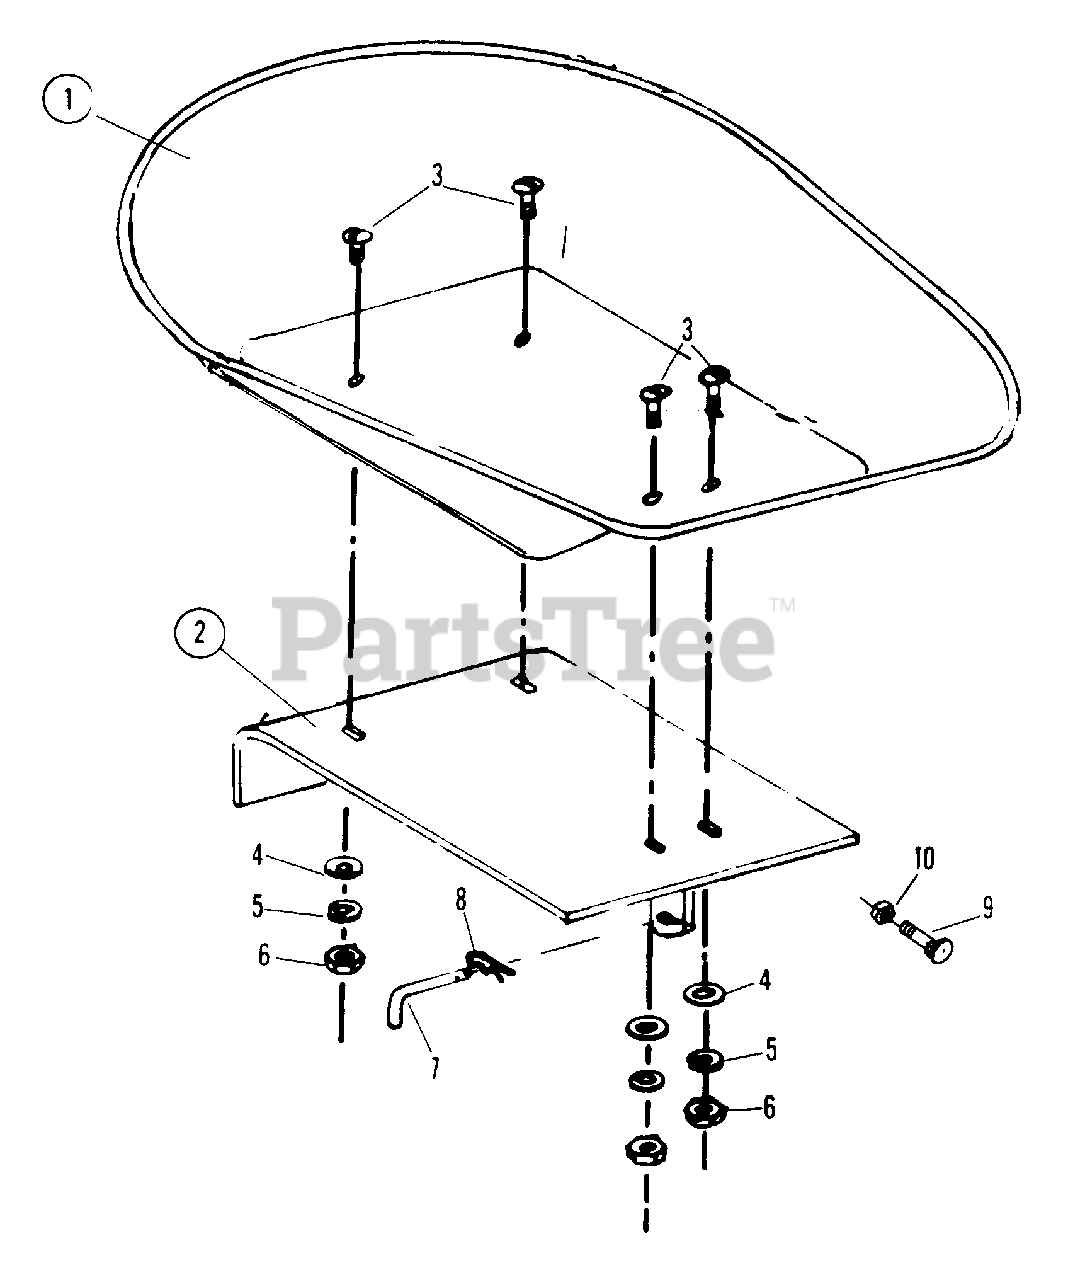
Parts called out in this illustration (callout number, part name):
1	TRAY, DUMP BARROW HAULING
2	BRACKET, TRAY MOUNTING
3	SCREW, 3/8 x 3/4 PAN HEAD MACHINE
4	WASHER, 3/8 PLAIN
5	LOCKWASHER, 3/8"
6	NUT, 3/8 HEX
7	L-PIN .5" Dia.
8	COTTER-PIN
9	BOLT, 1/2 x 2 CARRIAGE
10	LOCKNUT, 1/2" HEX
